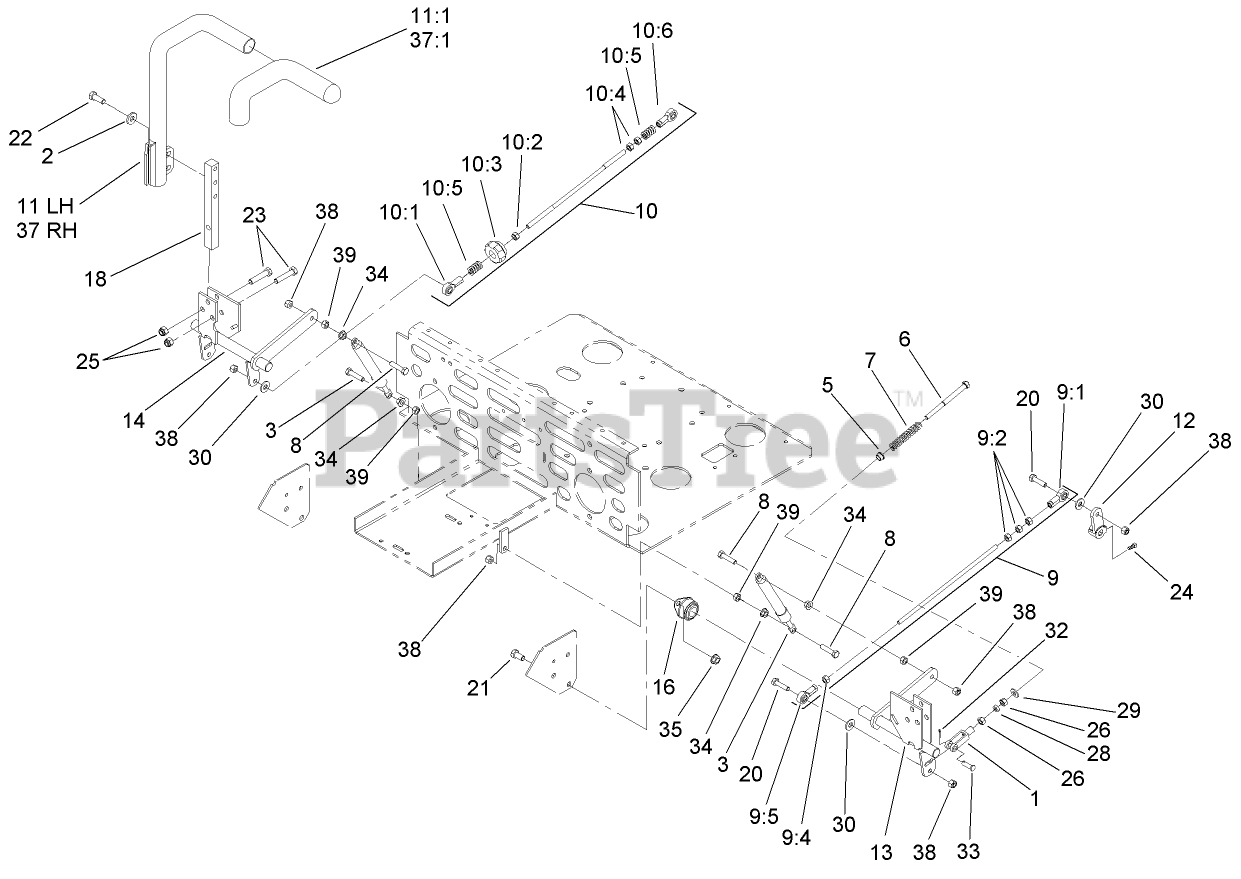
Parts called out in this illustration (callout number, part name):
1	YOKE-ADJUSTABLE
2	WASHER-BELLEVILLE
3	DAMPER-CONTROL, MOTION
5	BUSHING-FLANGED
6	BOLT-RETURN, NEUTRAL
7	SPRING-RETURN, NEUTRAL
8	SCREW-HH
9	Tracking Rod ASM
9:1	BALLJOINT-RH
9:2	NUT-HEX
9:5	BALLJOINT-LH
10	Tracking Rod ASM
10:1	BALLJOINT-RH
10:2	NUT-HEX
10:3	KNOB-TRACKING
10:5	SPRING-COMPRESSION
10:6	BALLJOINT-LH
11	LH LEVER ASM
11:1	Grip-Control, Motion
12	ARM-CONTROL, PUMP
13	Control-Motion, LH
14	Control-Motion, RH
16	BEARING-FLANGE, SIDE
18	ARM-SHAFT, CONTROL
20	SCREW-HH
21	SCREW-HH
22	SCREW-HH
23	SCREW-HH
24	SCREW-SET
25	NUT-LOCK, NI
26	NUT-HEX
28	NUT-JAM
29	WASHER-FLAT
30	WASHER-FLAT
32	PIN-COTTER
33	PIN-CLEVIS
34	NUT-HF
35	NUT-HHF, WHIZ
37	RH LEVER ASM
37:1	Grip-Control, Motion
38	NUT-LOCK, NI
39	NUT-HEX
